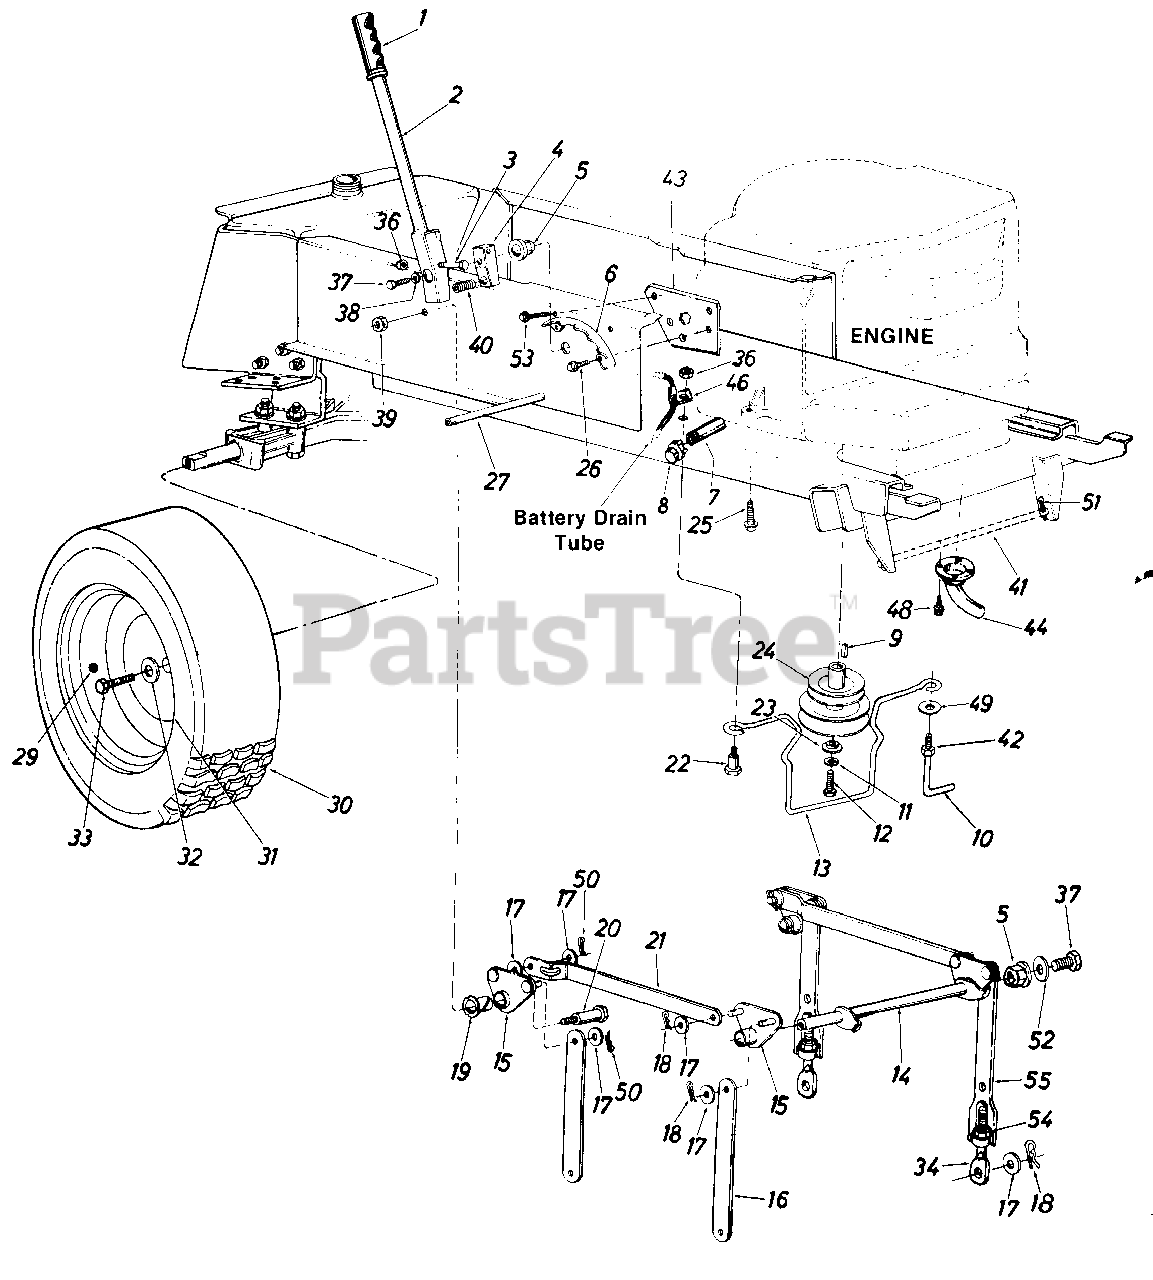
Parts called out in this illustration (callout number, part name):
1	Grip
2	Lift Handle Ass'y.
3	Hex Scr. 5/16-18 x 1.50" Lg.
4	Lift Shaft Drive
5	Plastic Hex Brg. 5/8" I.D.
8	Pipe Cap 3/8-18 Npt.
9	Sq. Key 1/4" x 1.50" Lg.
10	Belt Guard Lock Pin
11	L-Wash. 7/16" Scr.
12	Hex Scr. 7/16-20 x 1.50" Lg.
13	Belt Guard
14	Lift Shaft Ass'y.
15	Lift Pivot Brkt. Ass'y.
17	Fl-Wash. 1/2" I.D. x 1.00" O.D. x .090
18	Hairpin Cotter
19	Nyliner 5/8 I.D. x .88" Lg.
20	Shld. Scr. 5/8" Dia. x .96" Lg. 3/8-16
23	Flat Wash. .44" I.D. x 1.25" O.D. x .17
24	Two-Step Engine Pulley
25	Hex Wash. Hd. Scr. 3/8-16 x 1.25" Lg.
26	Hex Thd. Rolling Scr. 5/16-24 x .50" Lg.
27	Running Board Rod
29	Air Valve
30	Rear Wheel Ass'y. Comp.
31	Rear Wheel Rim Only
32	Bell-Wash. .345" I.D. x .88" OO.D.
33	Hex Bolt 5/16-24 x .75" Lg.
34	Eye Bolt Adj. Link 1/2-13 Thd.
36	Hex Cent. L-Nut 5/16-18 Thd.
37	Hex Scr. 5/16-24 x .62" Lg.
38	L-Wash. 5/16" Scr.
39	Hex Center L-Jam Nut 3/8-16 Thd.
40	Compression Spring
41	Deck Connecting Rod
42	Hex Nut 5/16-24 Thd.
46	Mounting Clamp
48	Hex Wash. Hd. AB-Tap Scr. #10 x .50" Lg.
49	Bel l-Wash. .39" I.D.
50	Cotter Pin .09 Dia. x 1.0" Lg.
51	Int. Cotter Pin
52	Flat Wash. .34" I.D. x 1.12" O.D. x .125
53	Hex Wash. Hd. AB-Tap Scr. 5/16 x .62" Lg.
54	Hex Nut 1/2-13 Thd.
55	Adj. Deck Link
